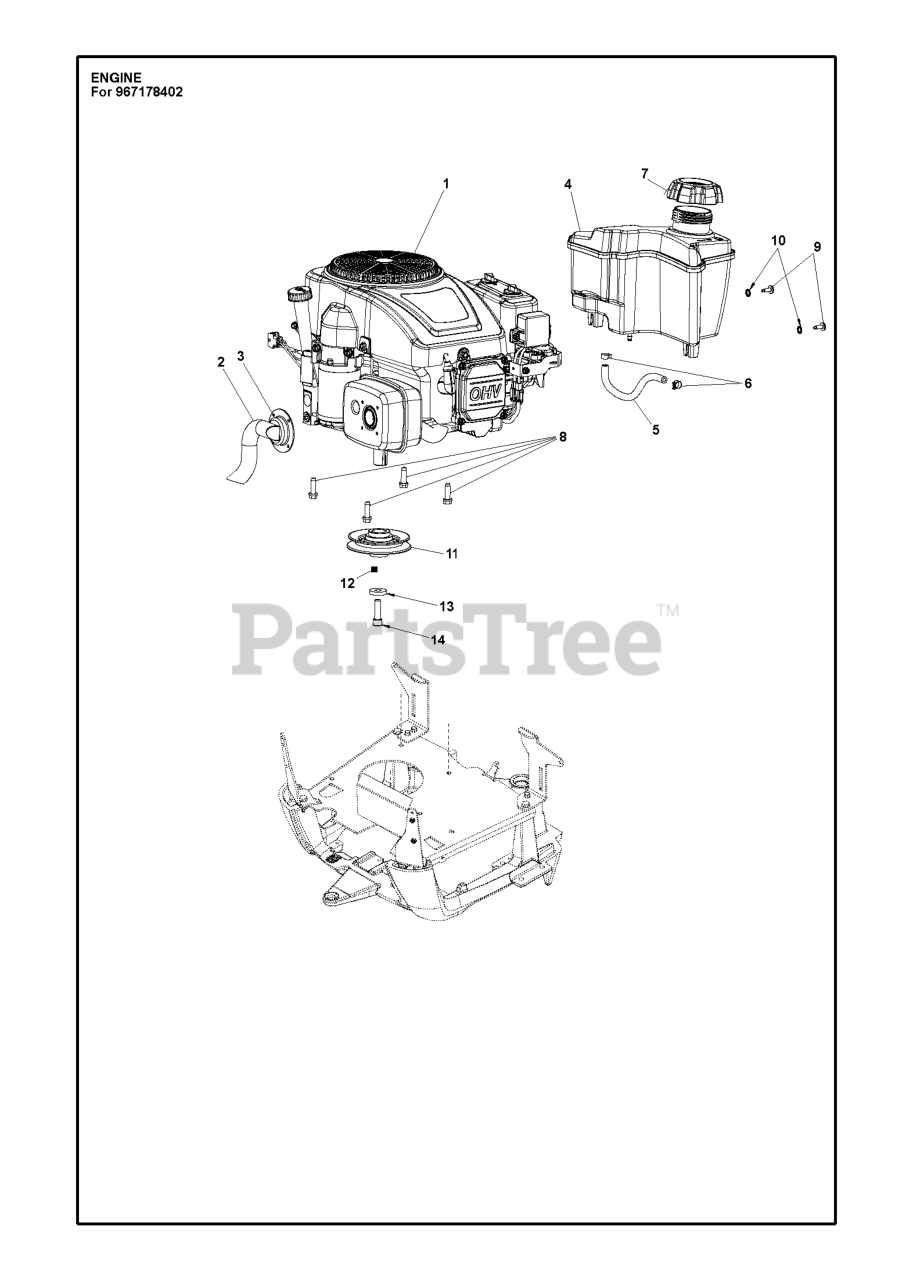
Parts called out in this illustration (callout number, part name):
3	SCREW ITXPANTT M5X10 ZPB (A00
7	CAP.ASSY.FUEL.3".N-EPA.GRY.498
8	BOLT 3/8-16X1-1/8
